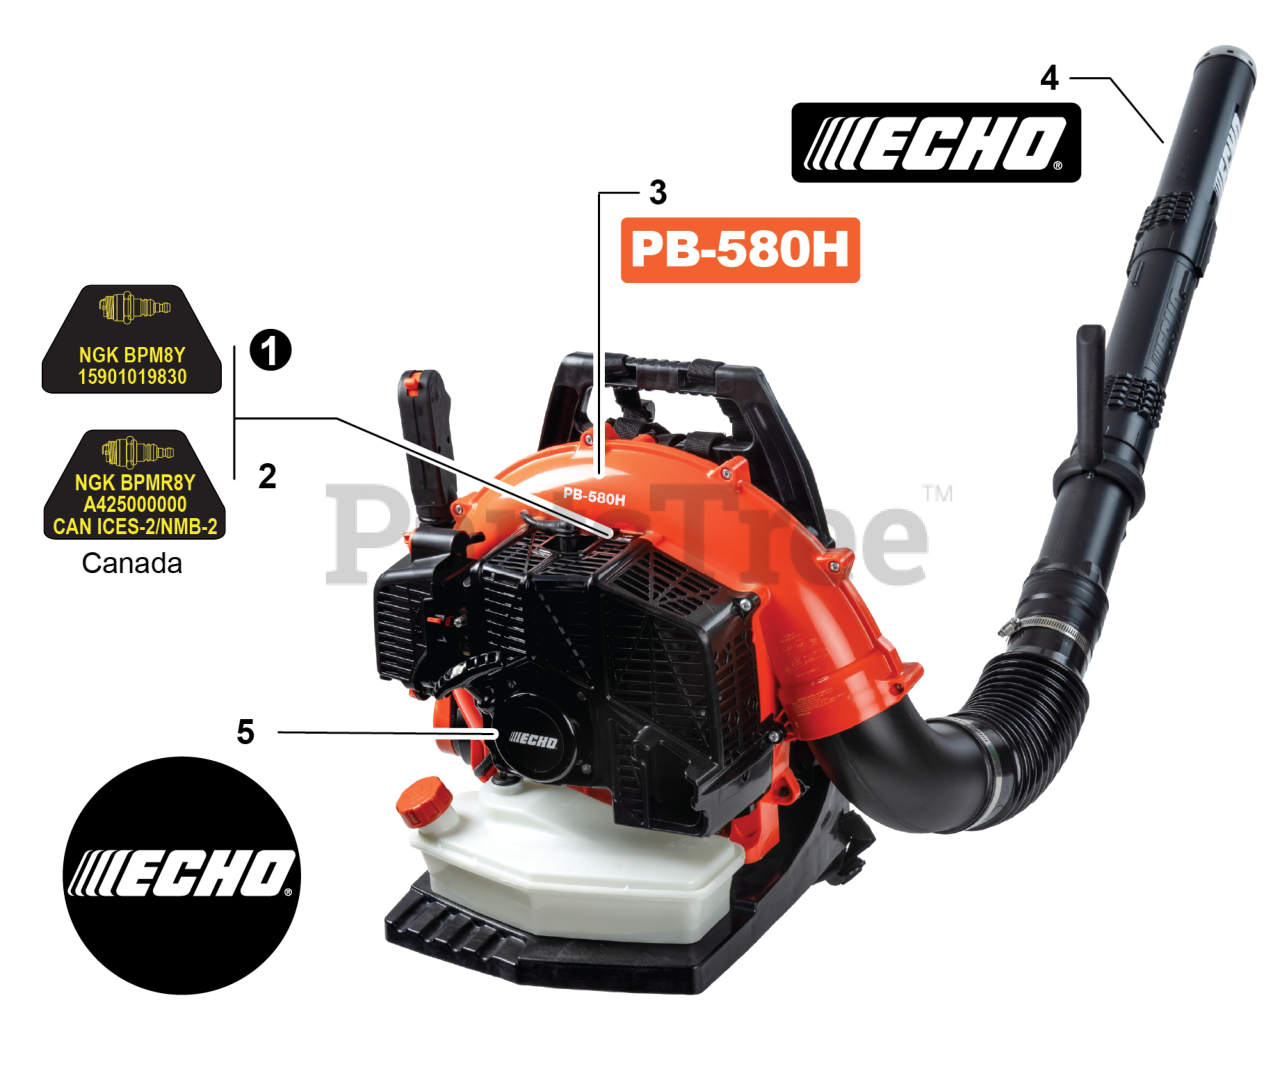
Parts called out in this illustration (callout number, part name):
1	LABEL - SPARK PLUG - BPM8Y
2	LABEL - SPARK PLUG - BPMR8Y
3	LABEL - MODEL - PB-580H
4	LABEL - ECHO
5	LABEL - STARTER - ECHO
